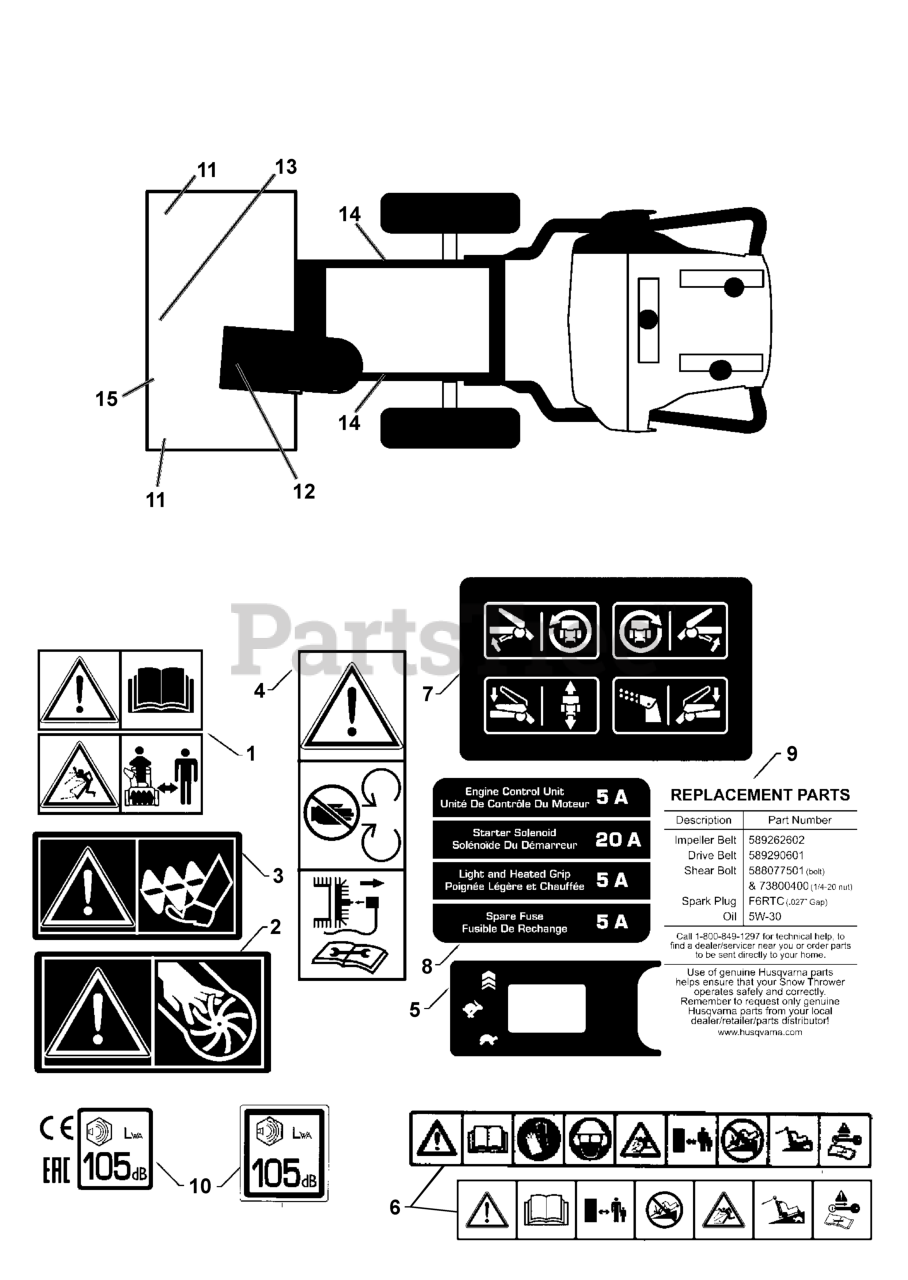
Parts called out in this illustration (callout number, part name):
1	DECAL.AUGER."
2	DECAL.CHUTE.SAFETY.EU/SC.17
3	DECAL.AUGER.SAFETY.
4	DECAL.BELT.GUARD.
5	DECAL SNOW CONSOLE GRAPHIC DEC
6	Decals
6	DECAL SNOW CONSOLE GRAPHIC DEC
7	DECAL SNOW CONSOLE GRAPHIC DEC
8	DECAL SNOW BATTERY BOX GRAPHIC
9	DECAL SNOW BATTERY BOX GRAPHIC
10	DECAL.NOISE.LEVEL.105DB/CE.EAC
10	DECAL.NOISE.LEV.105/CE.EAC.UKR
11	DECAL.AUGER.SAFETY.
12	DECAL.CHUTE.SAFETY.EU/SC.17
13	DECAL.AUGER."
14	DECAL.BELT.GUARD.
15	Decals
15	DECAL SNOW BUCKET TRIM GRAPHIC
